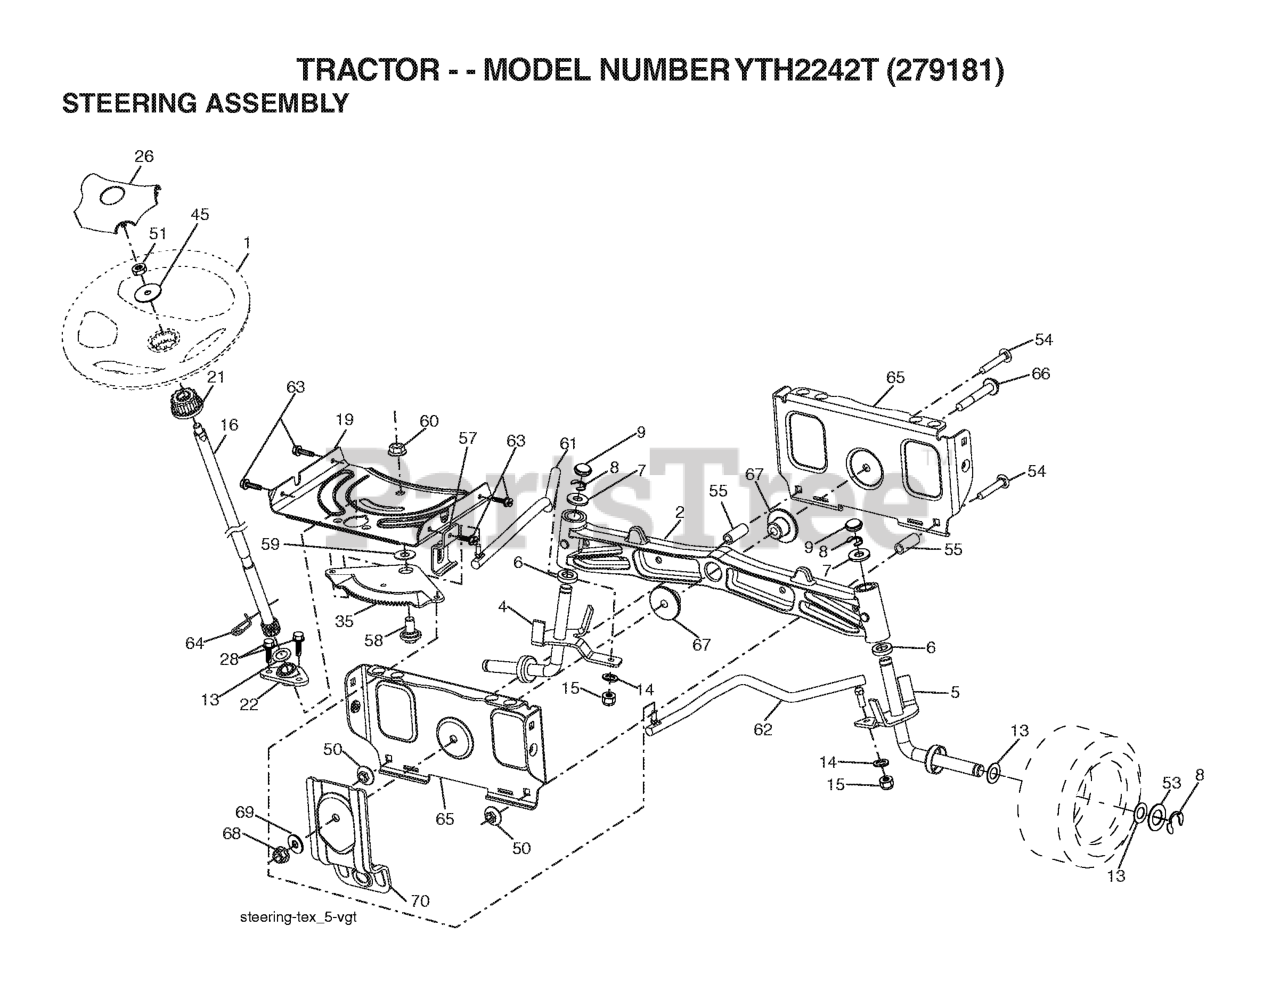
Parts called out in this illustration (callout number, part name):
1	WHEEL.STEERING.LEGEND2.GRY
2	AXLE.CAST.IRON
4	SPINDLE.WELDED.LH.15"TEX
5	SPINDLE.WELDED.RH.15"T
6	THRUST WASHER
9	CAP.SPINDLE.BLACK
14	WASHER, LOCK 3/8
15	NUT CROWNLOCK 3/8-24
16	SHAFT.STEER.STEALTH.DD
19	PLATE.STEER.DDL.NLT/NG
21	ADAPTER, WHEEL STNG..
22	BUSHING.ASM.STEERING.A
26	INSERT.CAP.STRG.WH.GRAY
28	SCREW, 3/8-16X3/4
35	GEAR.SECTOR.PLATE.DDL.
45	WASHER 9/16"ID, 2 3/8"OD
50	NUT LOCK FLG 3/8-16 UNC
51	NUT.HEX.1/2-20
53	WASHER.HARDENED
55	SPACER.BRACE.AXLE (2 2)
57	BRKT.UPSTOP.GT/LT.TEX
58	BOLT.SHOULDER.SECTOR.P
59	WASHER.THURST.SECTOR.S
60	NUT FLANGE LOCK 5/8-11
61	DRAGLINK.LH.BALLSTUD.D
62	DRAGLINK.RH.BALLSTUD.D
63	SCREW
64	RETAINER.CLIP.SPRING.S
65	BRACE.AXLE.FRONT.NLT/N
66	BOLT HEX FGHD 7/16-14 X 3 SERR
67	BUSHING.PM.FRONT AXLE
68	NUT.LOCK.FLANGE.7/16
69	WASHER.1.5X.505X.118
70	BRKT.DECK.SUSPENSION.F
